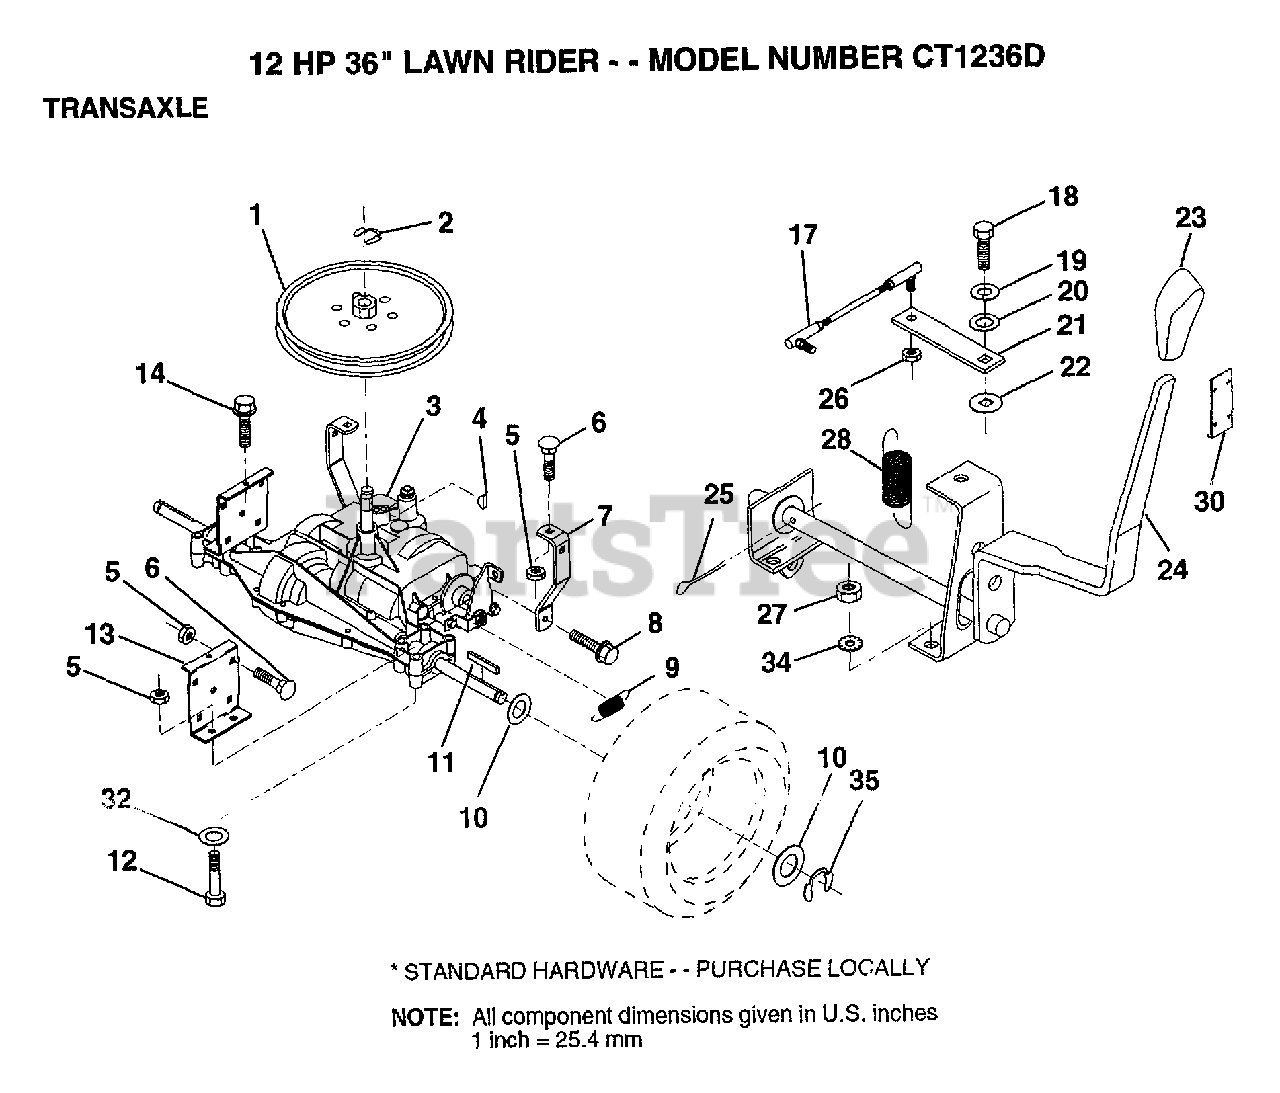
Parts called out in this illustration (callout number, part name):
1	PULLEY
6	BOLT
7	"STRAP,TORQUE"
8	SCREW LT
10	WASHER
11	SQUARE KEY
12	BOLT
13	"BRKT,TRANSAXLE"
14	SCREW
16	E-RING LT
17	LINK SHIFT
19	LOCKWASHER
20	WASHER LT
22	WASH-SHFT PLT LT
23	"KNOB,SHT CONTROL"
25	PIN COTTER 1/8
26	NUT.LOCK.5/16-24
28	"SPRING,EXT"
30	KNOB RETAINER
32	WASHER
34	LOCKWASHER.5/16.E
35	E-RING LT
